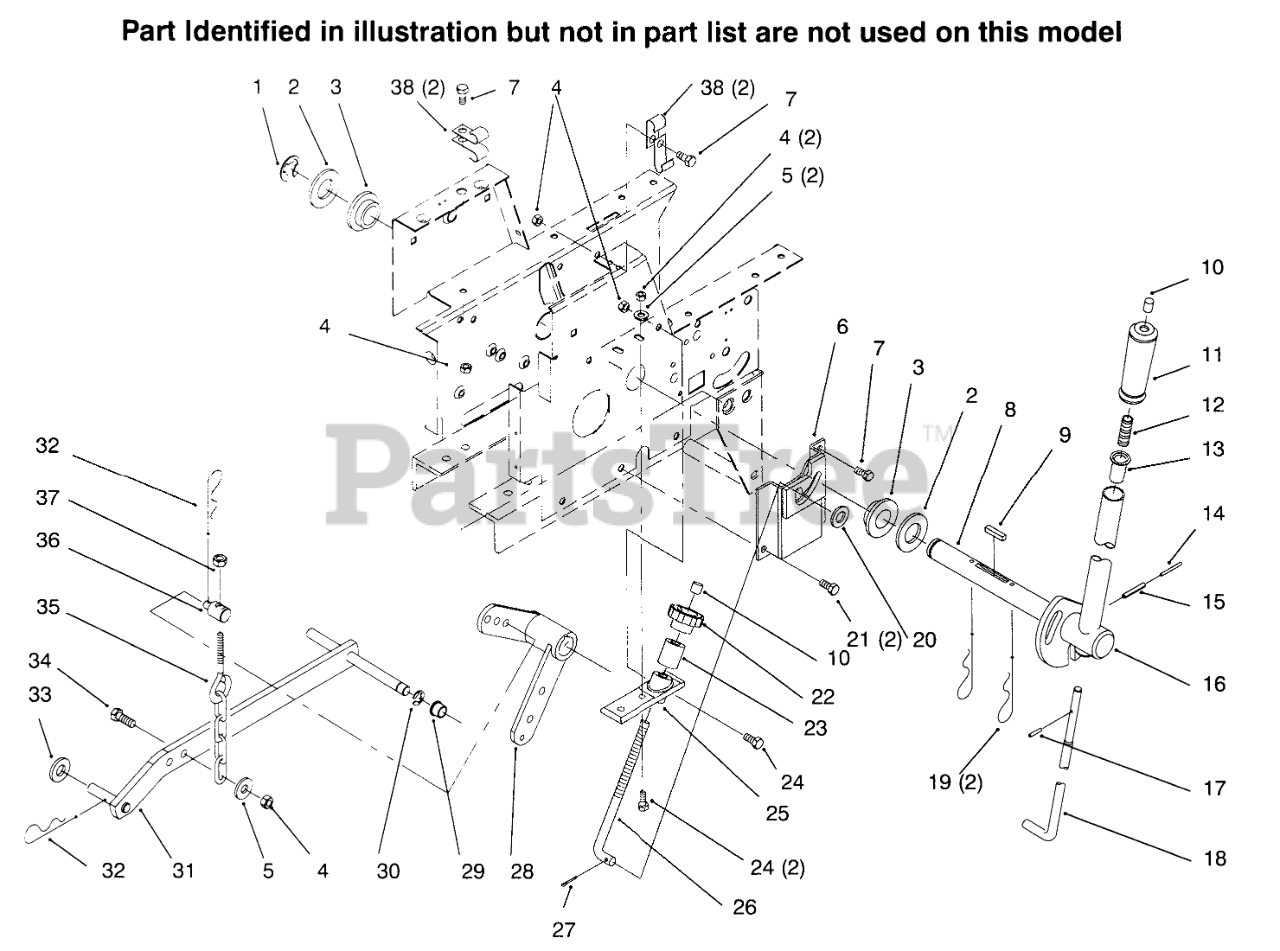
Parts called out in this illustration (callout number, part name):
1	RING-RETAINING
2	WASHER-FLAT
3	BEARING-FLANGE
4	NUT-LOCK, NI
5	WASHER-PLAIN
6	Latch Bracket
7	Bolt
8	SHAFT-LIFT LEVER
9	KEY-SQUARE
10	CAP-ROD, PLUNGER
11	GRIP-HANDLE
12	SPRING-COMPRESSION
13	RETAINER-SPRING
14	PIN-SPRING
15	PIN-ROLL
16	Lift Lever
17	PIN-SPIROL
18	ROD-LATCH LIFT
19	PIN-HAIR
20	WASHER-FLAT
21	SCREW-SELF TAP
22	KNOB-LIFT CONTROL
23	Sleeve
24	SCREW-HH
25	Casting
26	ROD-HEIGHT CONTROL
27	PIN-COTTER
28	LIFT LEVER ASM
29	BUSHING
30	RING-RETAINING, EXTERNAL
31	Bar-Lift
32	PIN-HAIR
33	WASHER-FLAT
34	SCREW-HH
35	CHAIN-LIFT
36	TRUNNION-LIFT
37	NUT-LOCK, NI
38	CLIP
39	SCREW-HH
